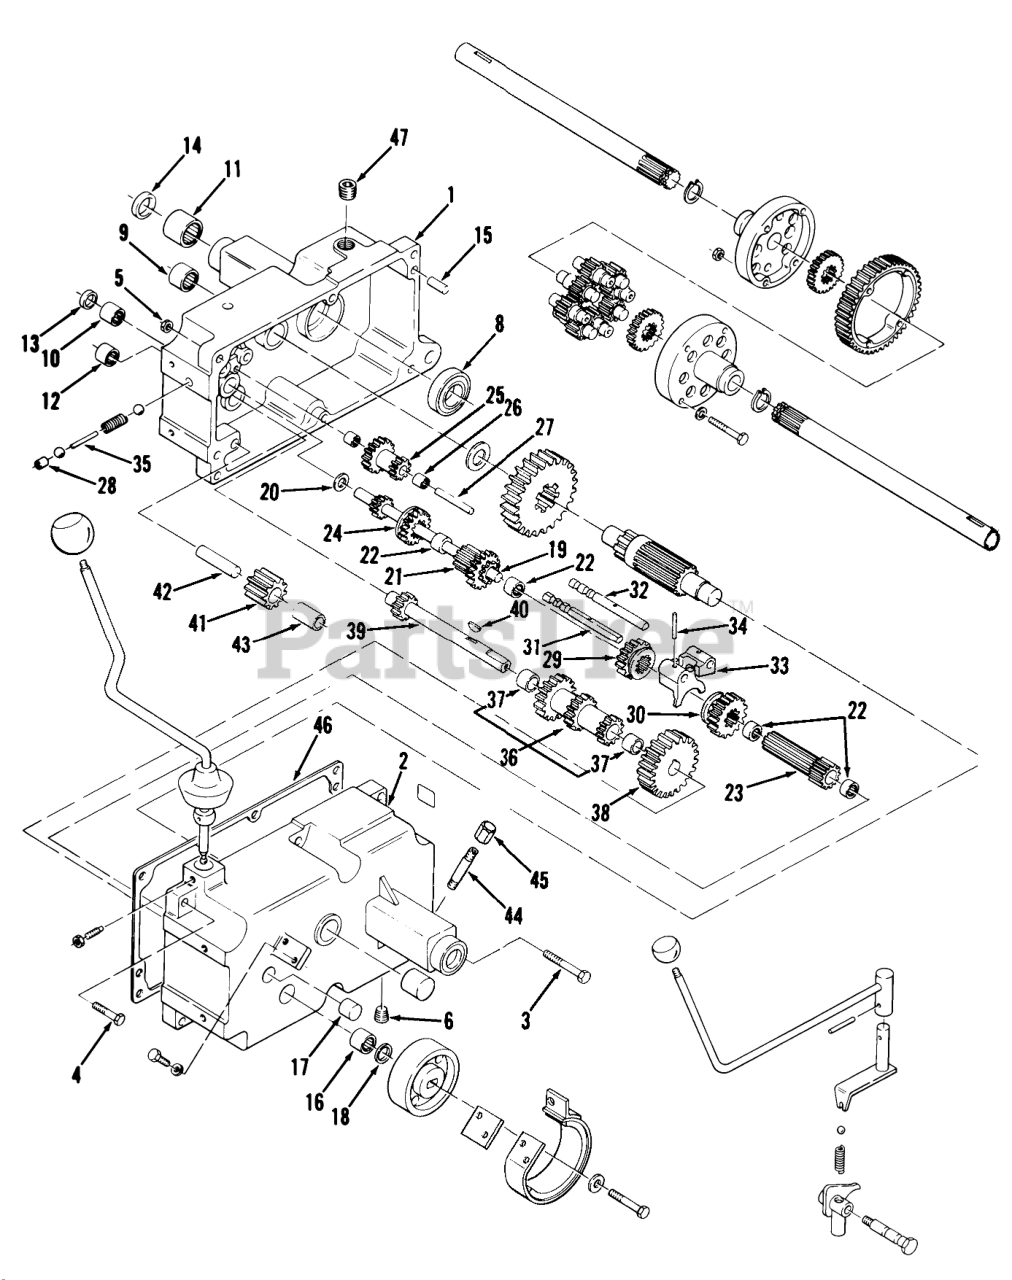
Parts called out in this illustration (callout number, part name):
1	Case RH
2	Case L.H.
3	HHCS
4	Bolt
5	Nut
6	PLUG 1/4 PIPE ALLEN
8	BALL BRG 1 1/2 I.D.
9	BEARING-NEEDLE
10	BEARING-NEEDLE
11	BEARING
12	BEARING-NEEDLE
13	SEAL-OIL
14	SEAL-OIL
15	PIN-DOWEL
16	BEARING-NEEDLE
17	Bearing Needle
18	SEAL-OIL
19	SHAFT-INPUT
20	WASHER-THR
21	GEAR
22	BEARING-NEEDLE
23	GEAR
24	GEAR-SLIDING
25	Gear
26	BEARING-NEEDLE
27	GEAR-SHAFT REDUCTION
28	CUP-PLUG
29	GEAR-HI AND 2ND
30	GEAR-LOW AND REVERSE
31	RAIL-SHIFT
32	RAIL-REAR SHIFT
33	FORK-SHIFT
34	PIN-ROLL
35	PIN-SHIFT
36	GEAR-CLUSTER
37	BUSHING-BRONZE
38	GEAR-CLUSTER SHAFT
39	Cluster Shaft
40	Key
41	GEAR/BUSHING ASM-REVERSE IDLER
42	PIN-DIFFERENTIAL
43	BUSHING
44	Nipple 3/8 x 1 1/2
45	Cap
46	GASKET-TRANSMISSION
